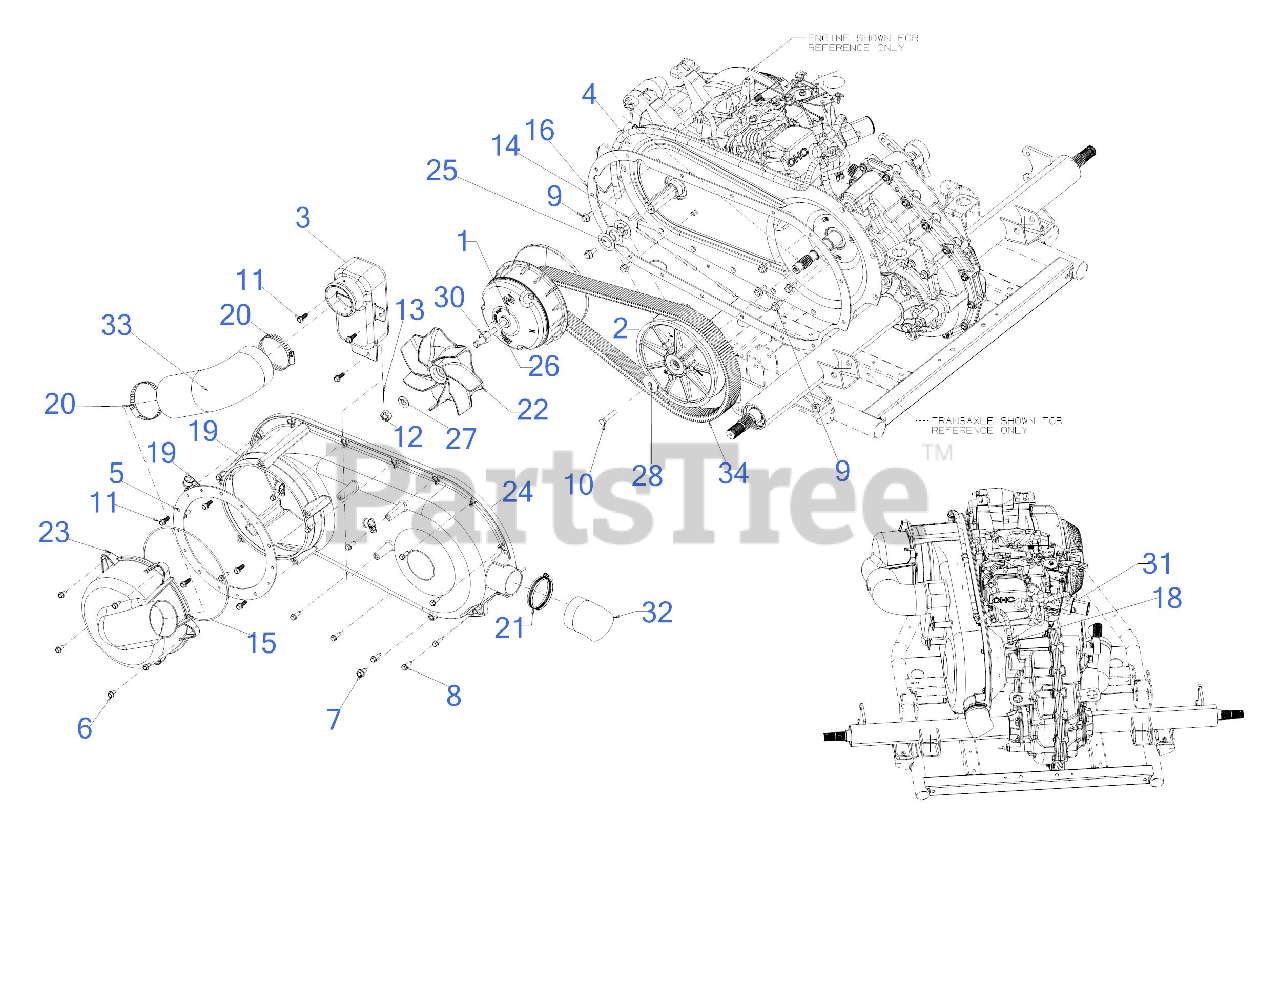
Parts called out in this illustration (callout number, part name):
1	DRIVER CVT CLUTCH ASSEMBLY
2	DRIVEN CVT CLUTCH ASSEMBLY
3	CVT FILTER HOUSING ASSEMBLY
4	BACK COVER PLATE
5	CVT MOUNTING PLATE
6	SCREW 1/4-20 X.500
7	SCREW 5/16-18 x .625
8	SCREW-TT 1/4-20 x .875
9	HEX FLANGE BOLT 5/16-24:0.75
10	SCREW 5/16-18 x 1.5 LG
11	SCREW 1/4-15 x .750
12	HEX NUT
13	COTTER PIN-3/32
14	SQUARE KEY (1/4 x 1.0)
15	O-RING 7.98 X 8.137 X 0.103
16	CVT COVER SEAL
18	HOSE CLAMP 1/20
20	HOSE CLAMP
21	HOSE CLAMP 2-3"
23	CVT FAN COVER
25	FLAT WASHER
26	FLAT WASHER
27	FLAT WASHER .510 x 1.00 x .060
28	FLAT WASHER
30	THREADED FAN ROD
31	FUEL HOSE LOW PERMEATION
32	CVT EXHAUST HOSE
33	CVT INTAKE TUBE
